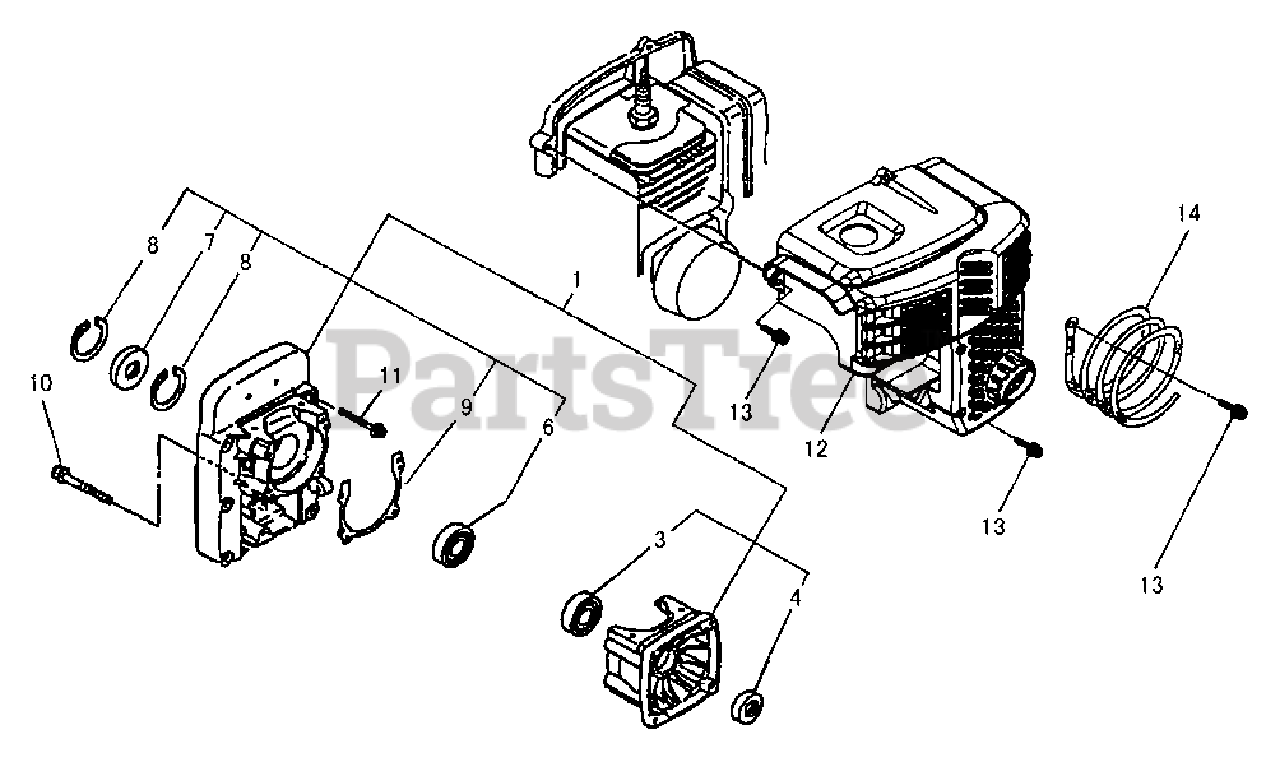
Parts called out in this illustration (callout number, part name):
1	CRANKCASE ASSY
3	BEARING, BALL
4	SEAL, OIL
6	BEARING, BALL
7	SEAL, OIL
8	RING, SNAP
9	GASKET
10	BOLT 5×30
11	BOLT, ADHESIVE M6×40
12	COVER, ENGINE
13	BOLT M5×20
14	WIRE, STATIC DISCHARGE 1050 MM
